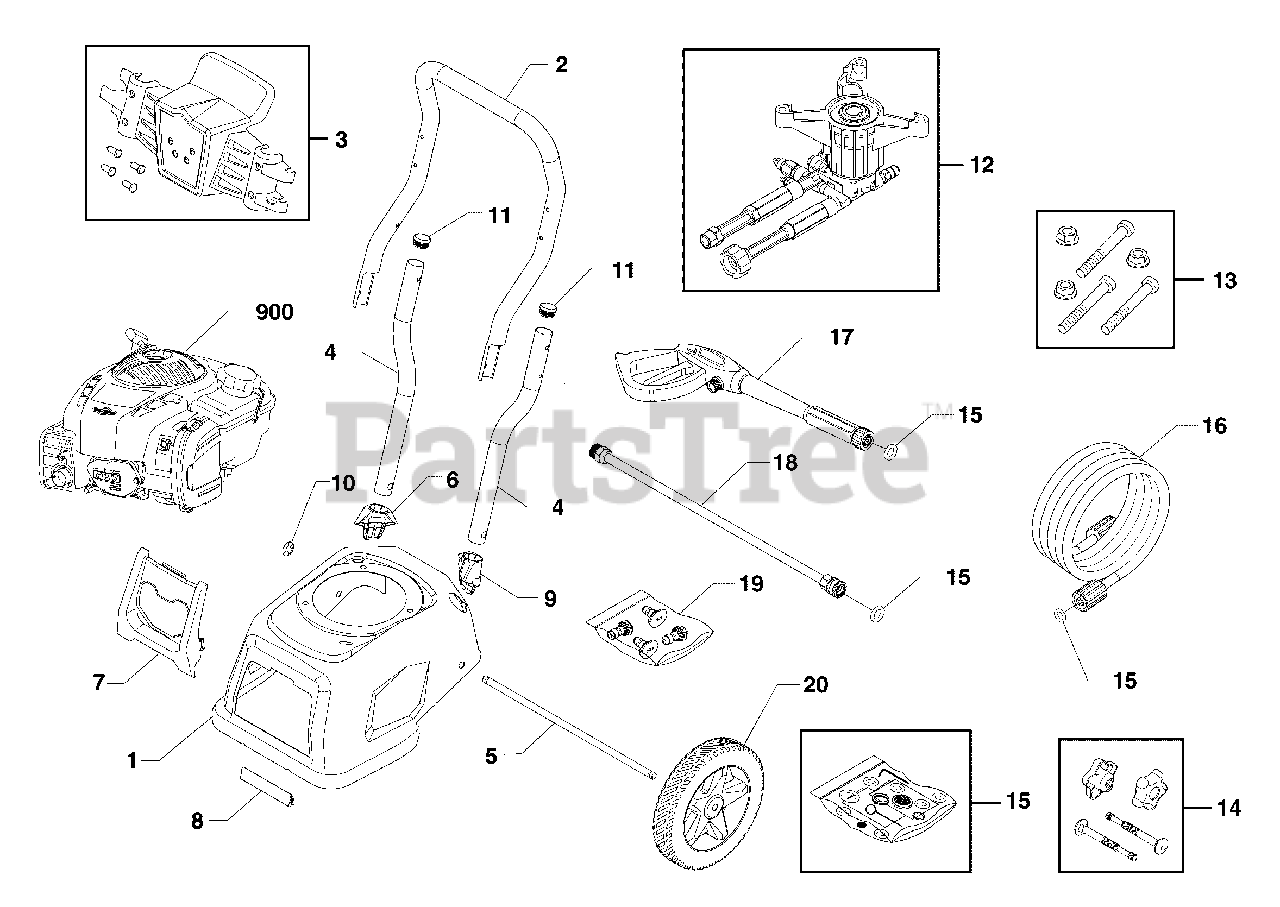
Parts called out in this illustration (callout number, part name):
1	SPRING, Connecting Rod
8	MOUNT-VIBRATION
13	KIT, Hardware, Pump Mounting
14	KIT, Hardware, Handle
15	KIT-O-RING MAINTENANCE
16	HOSE
17	GUN
18	EXTENSION, QC
19	KIT-QC NOZZLES
